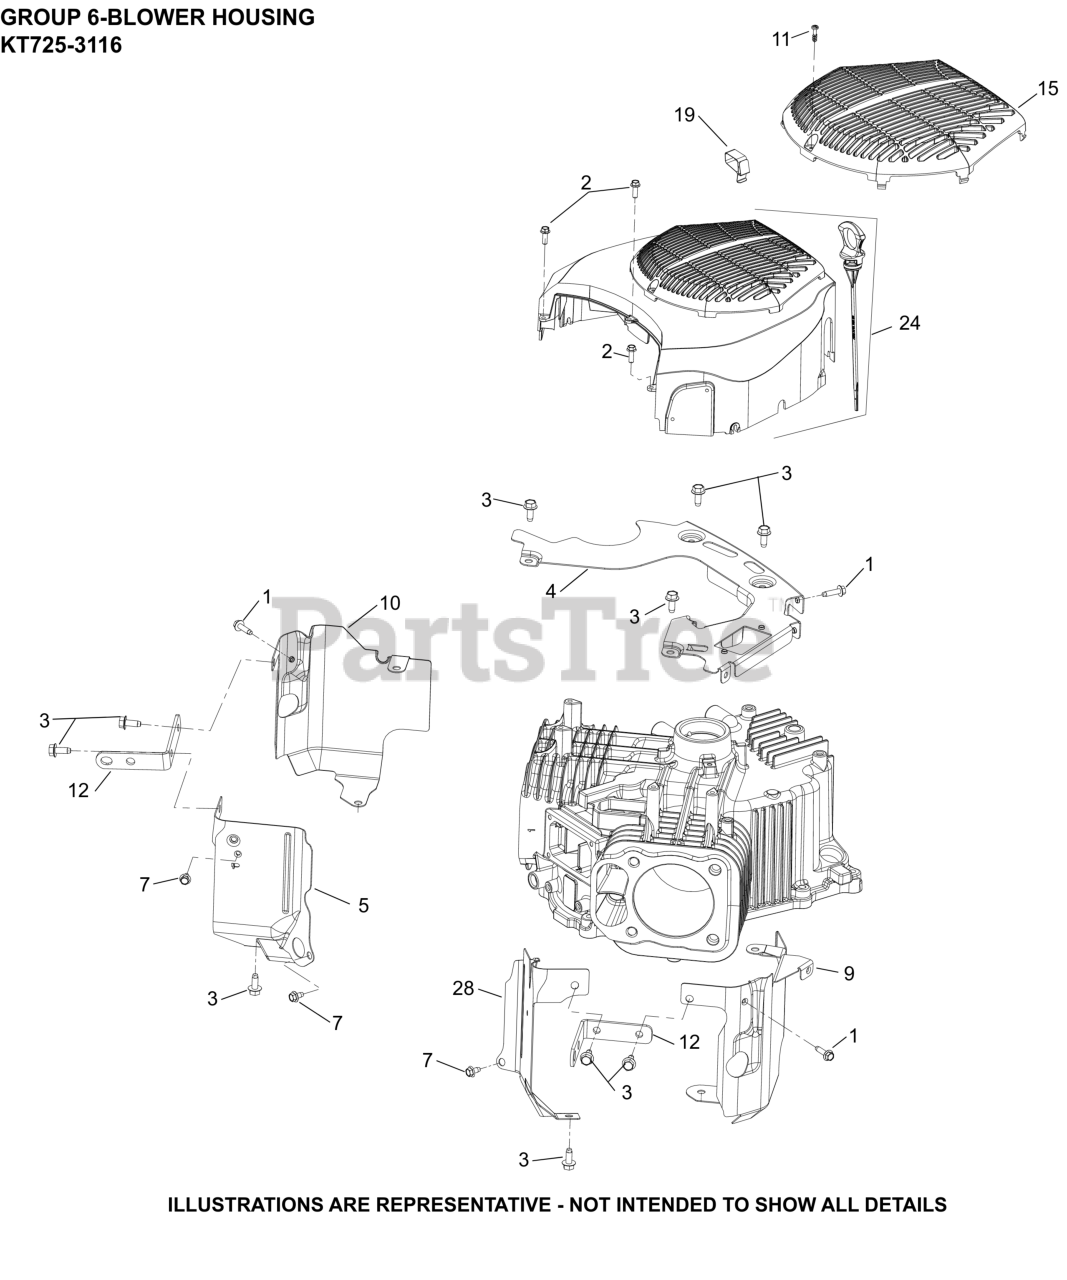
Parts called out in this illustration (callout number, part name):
1	SCREW, THD FRM-USE 25 086 473-S
2	SCREW, HI-LOW
3	SCREW, THREAD FORMING
4	PLATE, BACKING
5	BAFFLE, VALLEY #1
7	SCREW, THREAD FORMING
9	BAFFLE, LEFT BARREL
10	BAFFLE, RIGHT BARREL
11	SCREW, M5-2.42 (PT) THREAD
12	STRAP, LIFTING
15	GUARD, FIXED
19	CLIP, BLOWER HOUSING
24	KIT, BLOWER HOUSING
28	BAFFLE, VALLEY #2
